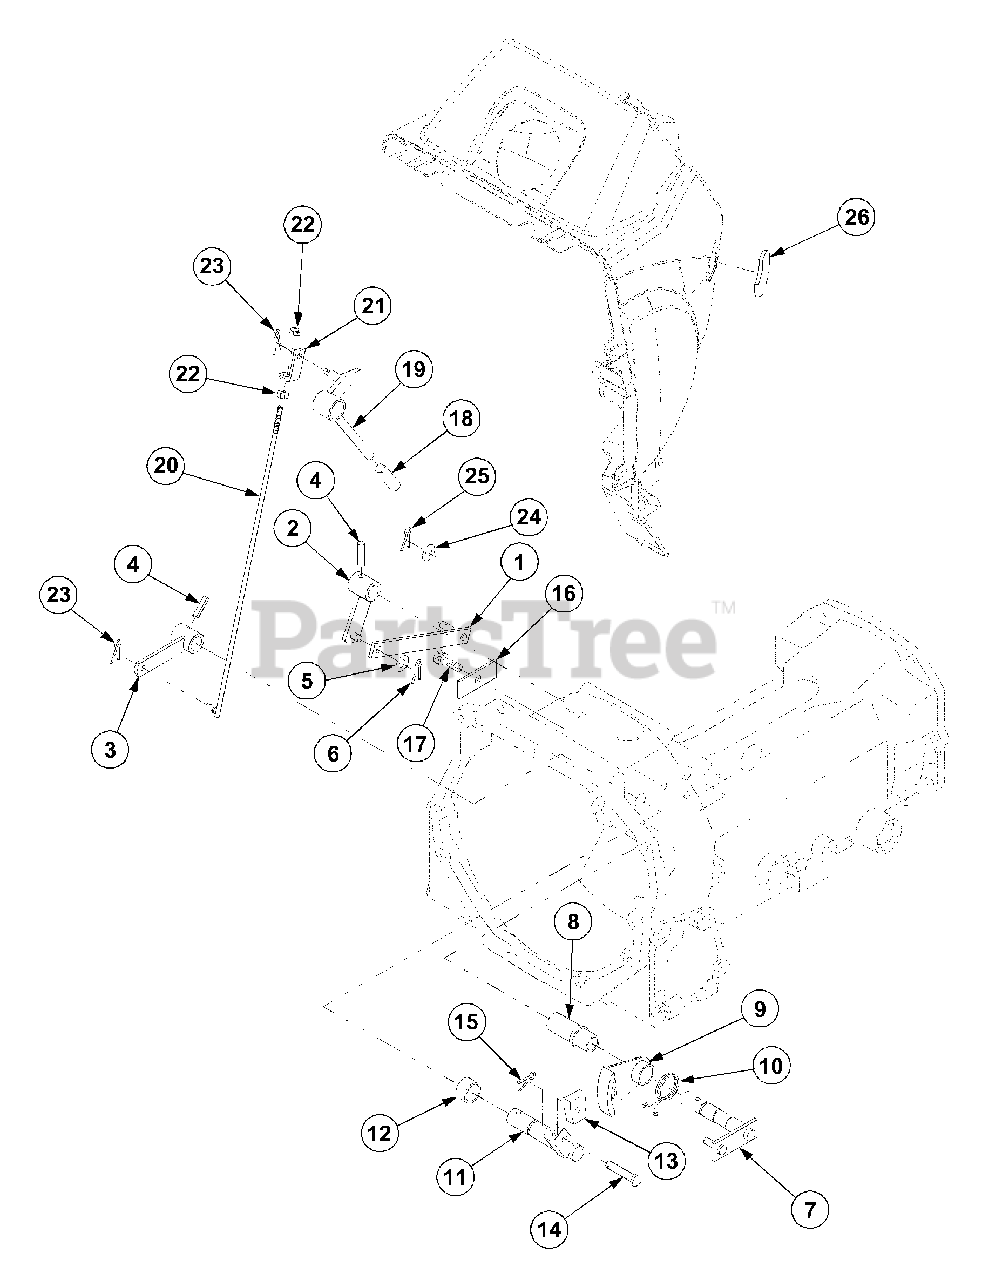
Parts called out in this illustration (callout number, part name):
1	Plate,Speed Con
2	Link,Speed Con
3	Arm,Speed Con
6	Pin,Split
15	Pin,Split
17	Bolt,w/Washer
19	Lever,Speed Con
20	Rod,Speed Con
23	Pin,Split
25	Pin,Split
